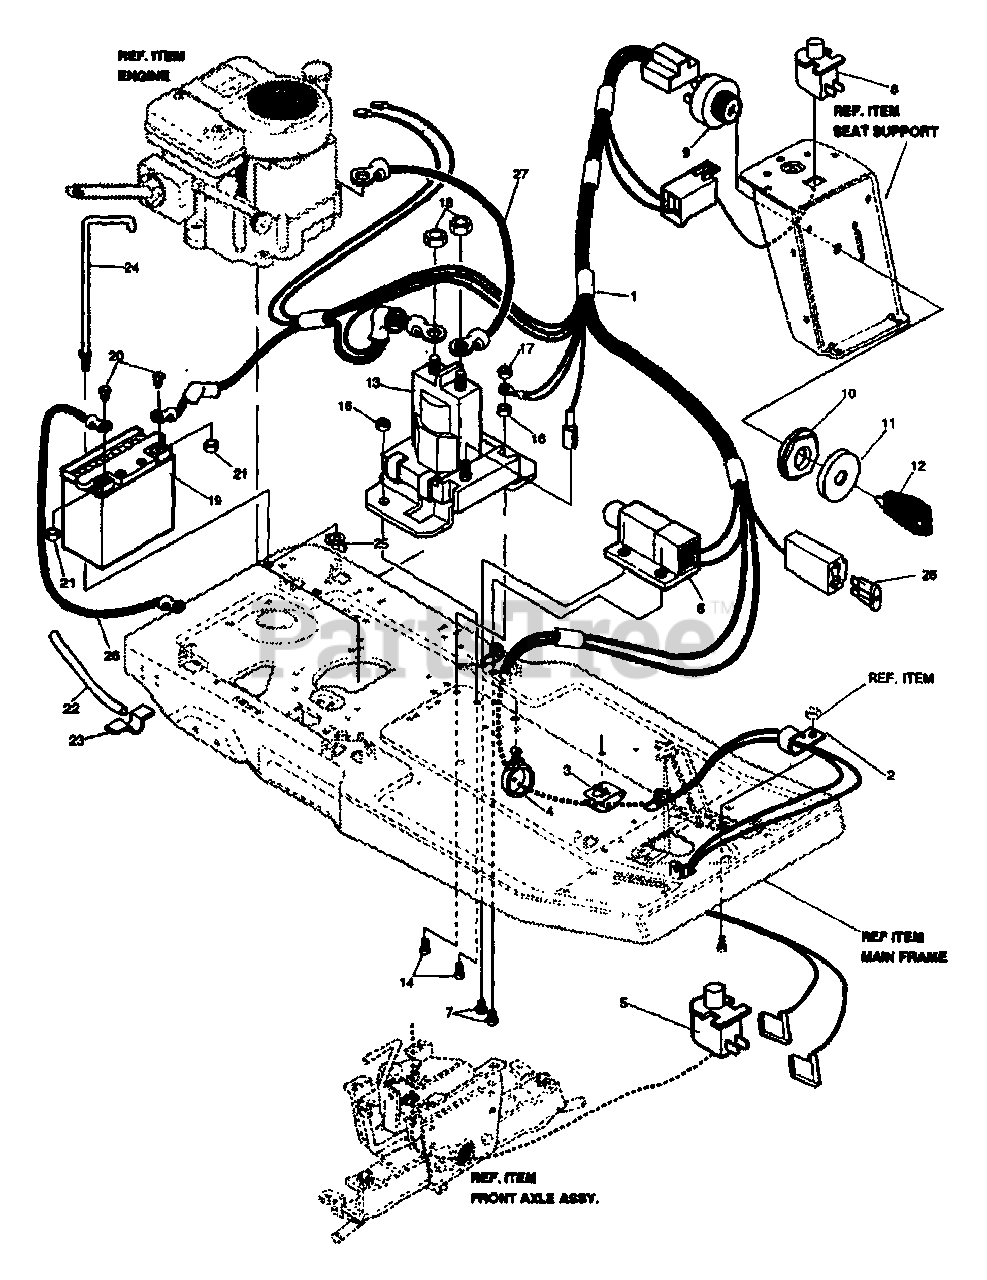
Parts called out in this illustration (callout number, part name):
1	HARNESS, ELEC RER C2 8-11 B&S
2	RETAINER, .31 ID X .62 X .03 WIRE
3	CLIP, TRW #C4490-022-27
4	CLIP, WIRE ROUTING, SNAP-IN
5	SWITCH, SNAP MNT NO. .055/.116
6	SWITCH, SCR MNT DP NC
7	SCREW, #12 X.50 PH PNH TAP
8	SWITCH,SNAP MNT NC .140
9	SWITCH, IGNITION W/O LIGHTS
10	NUT, 5/8-32 IGN SWIT
11	BOOT,SWITCH
12	KEY, IGNITlON SWITCH
13	SOLENOID. NEW CLUM
14	SCREW, 1/4-20 X.75 HX SEM MA
16	NUT, 1/4-20 REG HEX CTR LK
17	NUT, 1/4-20 REG HEX KEPS
18	NUT, 5/16-24 HKEPS
19	BATTERY, YUASA 12N14
20	SCR., METRIC, 6 X 1 X 11
21	NUT, METRIC, 6 X 1 HEX
22	DRAIN TUBE, BATT
23	CUP, 1.880 LG .255 ID PRESS WIRE
24	HOLD DOWN BRKT
25	NUT, WING 1/4-20 NYLON
26	WIRE, GROUND, 12.5"
27	WIRE. STARTER,
28	FUSE SPADE TYPE 32V 15A
